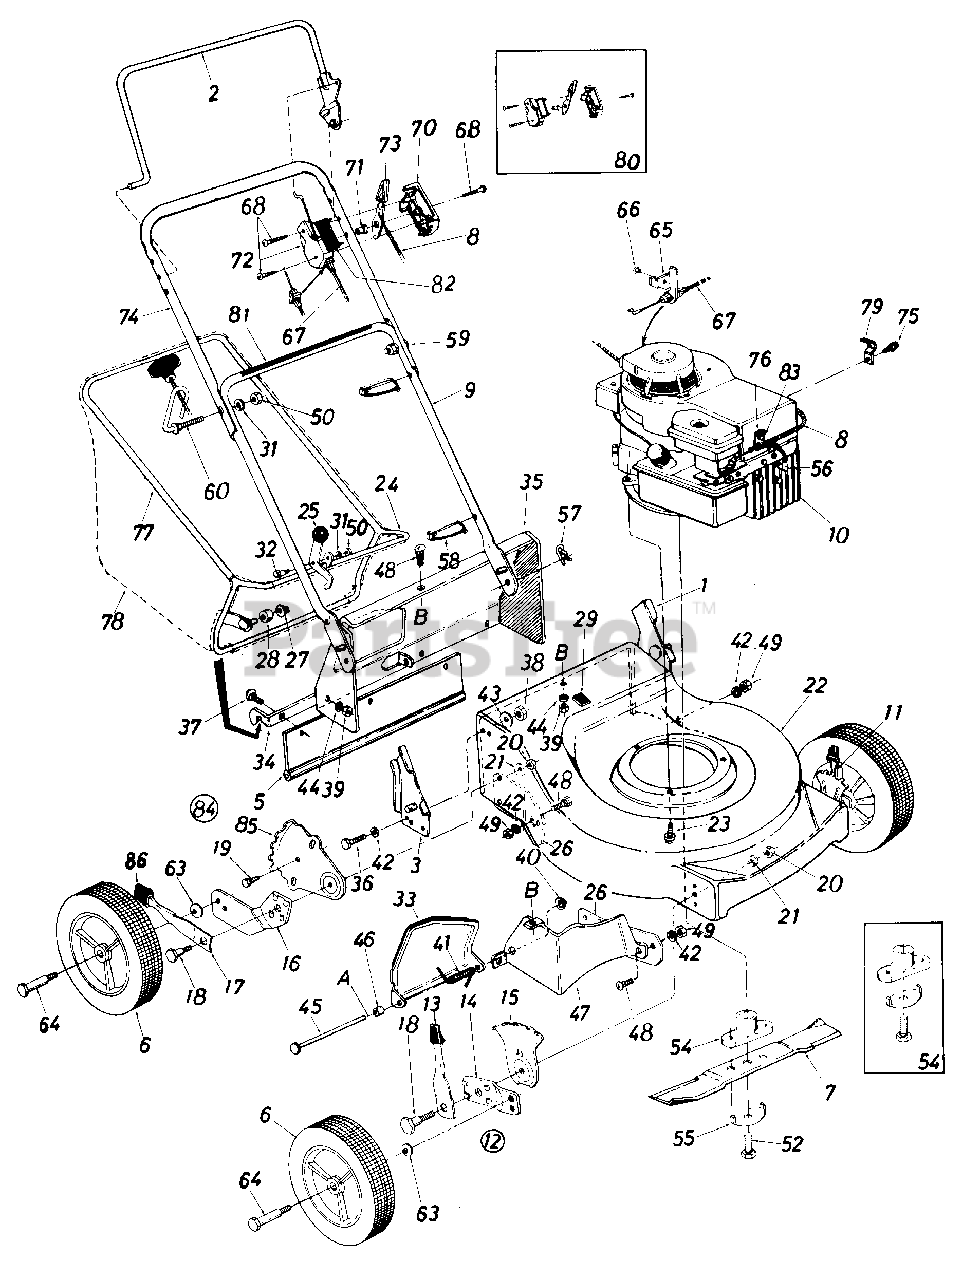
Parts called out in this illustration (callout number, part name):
1	Handle Brkt. Ass'y.-L.H.
2	Control Handle Ass'y.
3	Handle Brkt. Ass'y.-R.H.
5	Rear Flap Ass'y.
6	Wheel Ass'y.
7	21" Blade
8	Throttle Wire-58"
9	Lower Handle (Painted)
10	Engine
11	1 Front L.H Height Adj. Ass'y.
12	Front R.H. Height Adj. Ass'y.
13	Spring Lever Ass'y. w/Knob
15	Front Index Plate
16	Rear Pivot Bar-R.H.
17	Spring Lever
18	Shld. Bolt .50" Dia. x .375
19	Hex Wash. Hd. Tap Scr. 1/4 x.62" Lg.
20	Hex Nut 3/8-16 Thd.
21	Bell-Wash. .39" I.D. x .38"
24	Catcher Lower Frame Ass'y.
25	Cam Lever Grip Ass'y.
26	Baffle
27	Push Nut 3/8" Rod
28	Plastic Roller
29	Plastic Plug
31	L-Wash. 5/16" I.D.
32	Shld. Bolt .437" Dia. x .180"
33	Chute Door
34	Grass Catcher Hitch Brkt.
35	Rear Deck Section
36	Hex Bolt 1/4-28 x .75" Lg.
37	Carr. Bolt 1/4-20 x .75" Lg.*
38	Hex Nut 1/4-28 Thd.
39	Sems Nut 1/4-20 Thd.
40	Push Nut 1/4" Rod
41	Torsion Spring
42	L-Wash. 1/4" I.D.
43	Bell-Wash. 1/4" I.D. x .88"
44	Fl-Wash. .385" I.D. x 1.25"
45	Hinge Pin
46	Spacer .262" I.D. x .58" Lg.
47	Rear Baffle
48	Carriage Bolt 1/4-20 x .50"
49	Hex Nut 1/4-20 Thd.
50	Hex Nut 5/16-18 Thd.
52	Hex Bolt 3/8-24 x 1.5" Lg. (Grade 5)
54	Blade Adapter Kit
55	Blade Bell-Wash.
56	Spark Plug Boot
57	Intern. Cot. Pin 5/16" Dia.
58	Cable Tie
59	Curved Carriage Bolt 5/16-18 x 1.38" Lg.
60	Rope Guide Bolt
63	Bell-Wash. .400" I.D. x .88" O.D. x .060
64	Axle Bolt
65	Cable Bracket
66	Pop Rivet
67	Brake Control Cable 43"
68	Truss Mach. Hd. "B" Tap Scr. #12 x 1.50" Lg.
70	Control Panel Half
71	Control Disc Pin
72	Clutch Panel Half
73	Throttle Control Lever
74	Upper Handle (Painted)
75	Hex B-Tap Scr. #10 x .38" Lg.
76	Casing Clamp
77	Catcher Upper Frame
78	Grass Bag (Without Flip Top)
79	Casing Clamp
80	Control Housing Comp.
81	Instruction Label-Handle
82	Control Label-Throttle
83	Hex Wash. Hd. AB-Tap Scr. #8 x .38" Lg.
84	Rear Height Adj. Ass'y.-R.H.
85	Rear Index Plate
86	Spring Lever Knob
